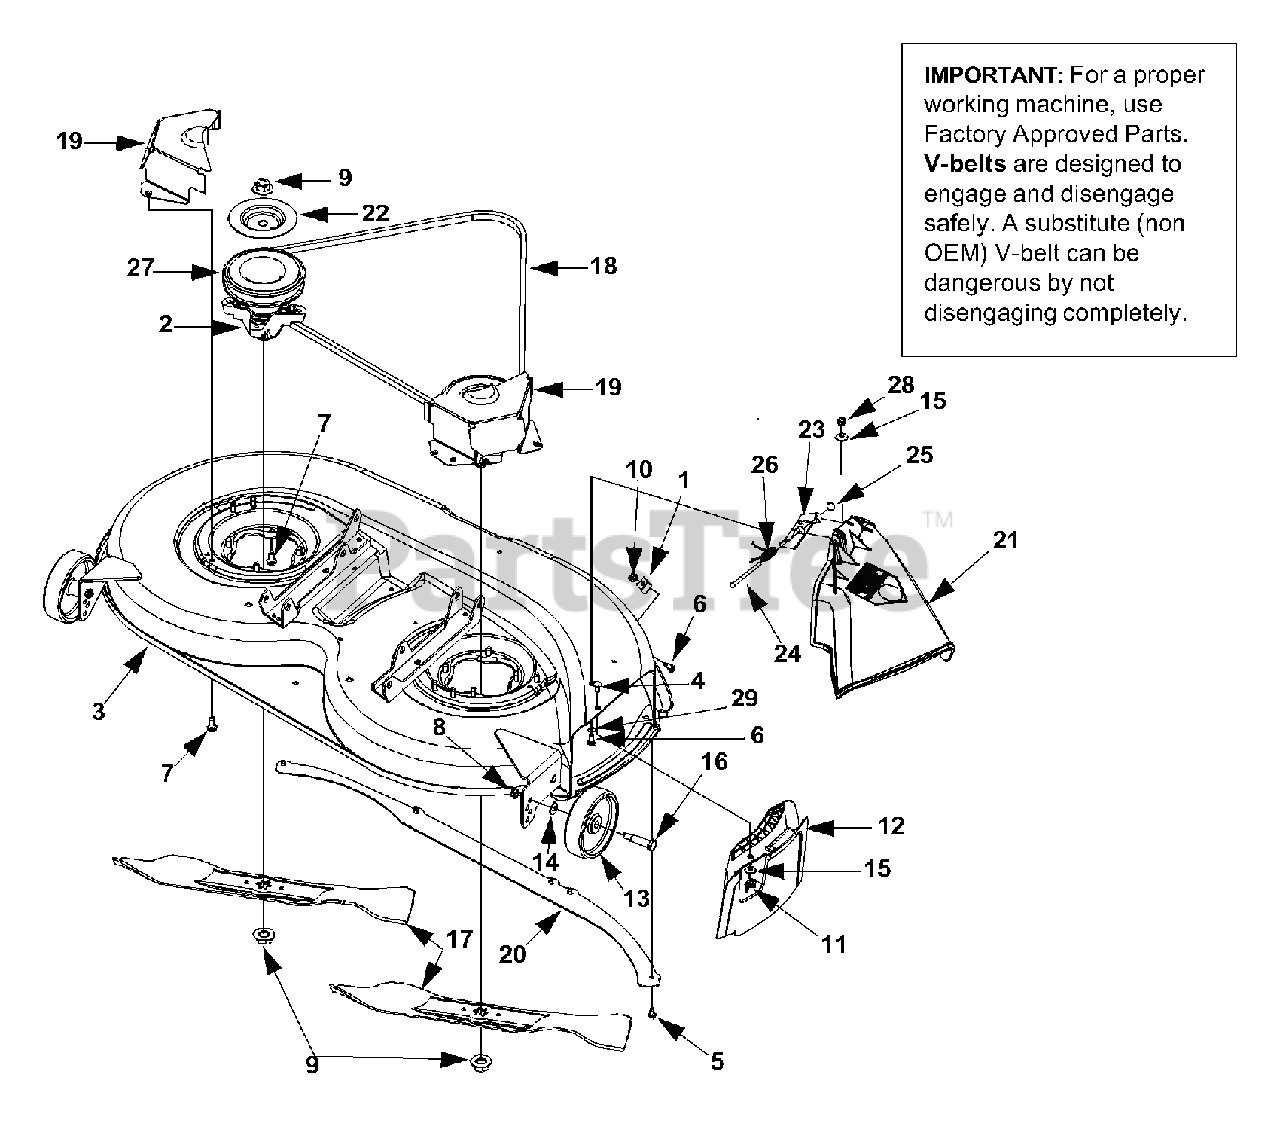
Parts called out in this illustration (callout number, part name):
1	Retainer Hook Brkt.
2	Blade Spindle Ass'y
5	Hex Wash. Hd. TT-Tap Screw 1/4-20 Thd.
6	Hex Bolt 1/4-20 x .62"
7	Hex Wash. TT-Tap Scr. 5/16-18 x .75"
8	Jam Nut 3/8-16
9	Hex Flange Nut 5/8-18 Thd.
10	Hex Flange Nut 1/4-20 Thd.
11	WIng Nut 1/4-20
12	Mulch Plug
13	Deck Wheel-5"
14	Bell-Wash. .40" I.D. x .88" O.D.
15	Bell-Wash. 1/4 I.D.
16	Shoulder Screw
17	3 in 1 blade
18	V Belt
21	Chute Ass'y
22	Brake Disc.
23	Hinge Mounting Brkt.
24	Hinge Pin
25	Speed Nut Cap
26	Torsion Spring
27	5.75" Dia. Pulley
28	Hex Nut 1/4-20 Gr. 5
29	Push Nut
